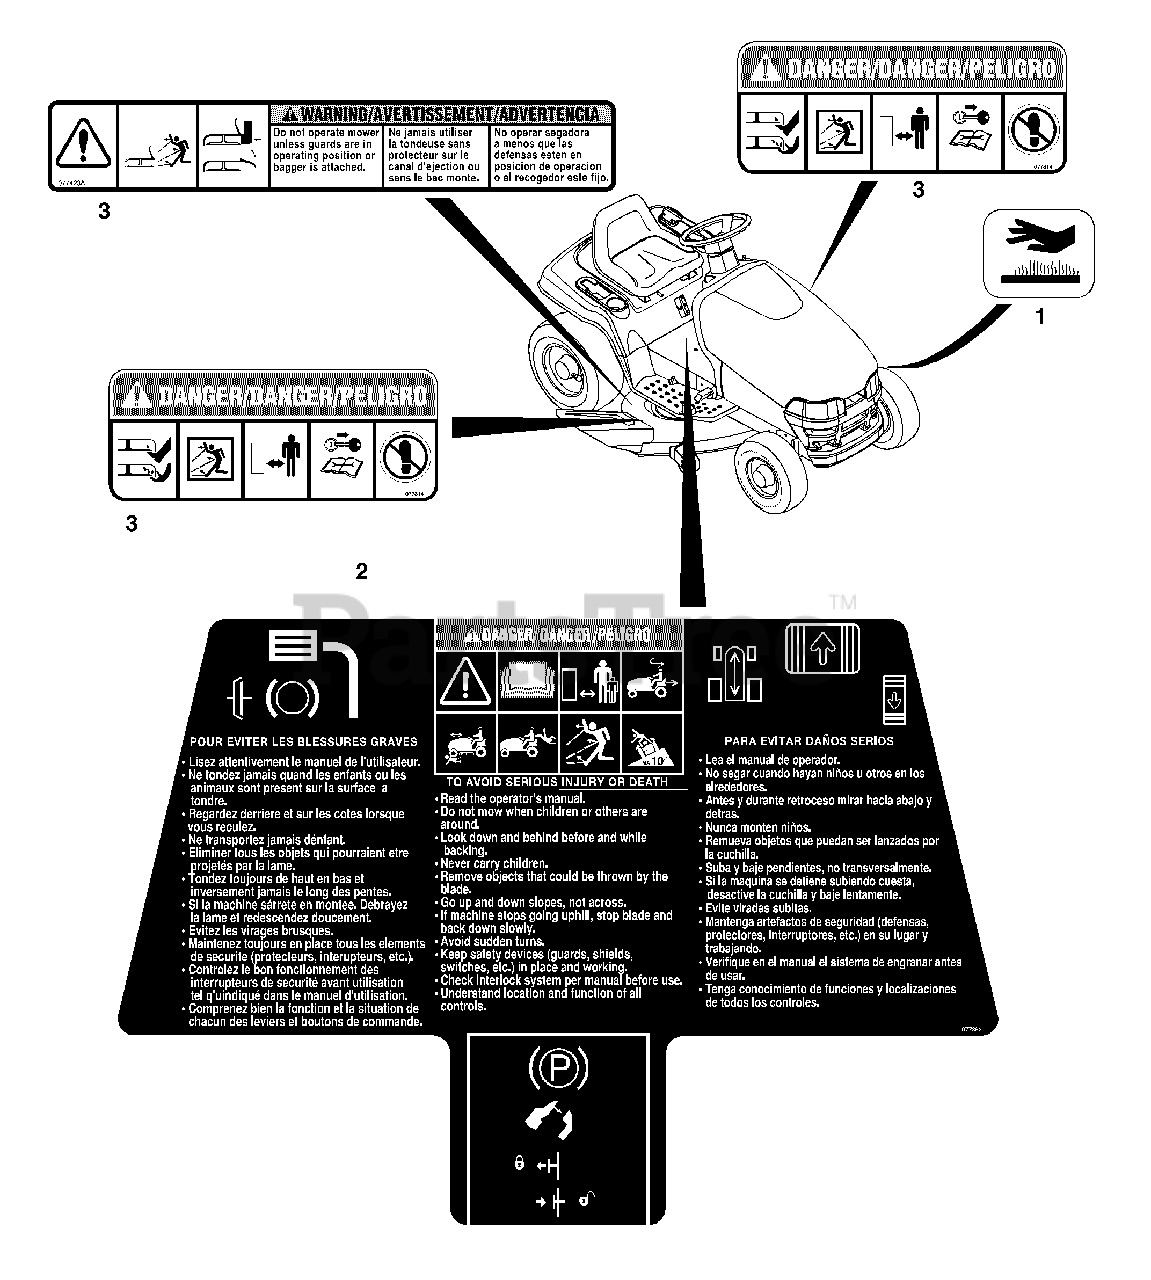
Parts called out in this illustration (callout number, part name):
1	DECAL, HOT SURFACE
2	DECAL OPERATING INSTRUCTIONS
3	DECAL SET - DECK
